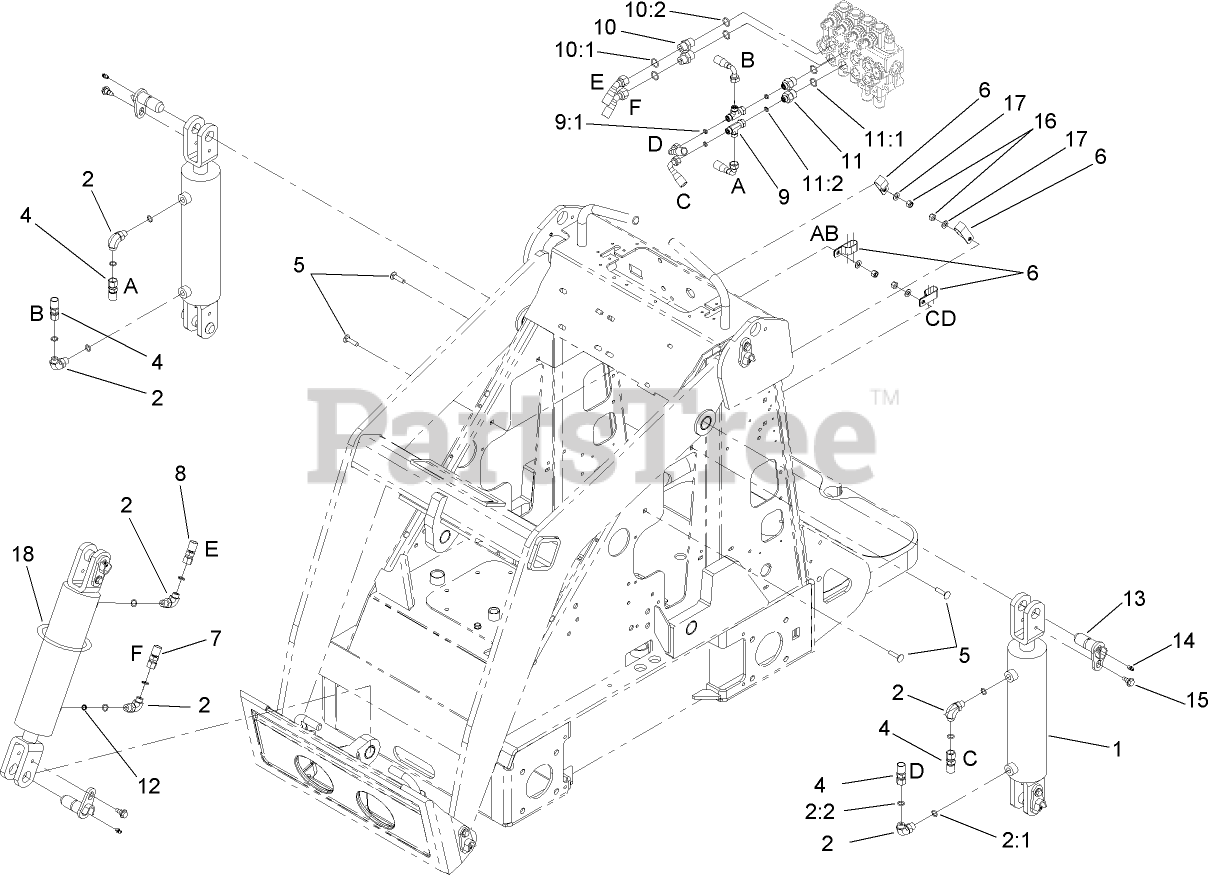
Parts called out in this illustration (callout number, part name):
1	CYLINDER-HYD
2	FITTING-ELBOW 90
2:1	O-RING
2:2	O-RING
4	HOSE-HYD
5	SCREW-CARR
6	CLAMP-R, DOUBLE
7	HOSE-HYD
8	HOSE-HYD
9	FITTING-HYD
9:1	O-Ring
10	FITTING-STRAIGHT
10:1	O-RING
10:2	O-RING
11	FITTING-STR
11:1	O-RING
11:2	O-RING
12	ORIFICE-PORT INSERT, ONE WAY
13	PIN-PIVOT
14	FITTING-GREASE
15	BOLT-SHOULDER
16	NUT-LOCK, NI
17	WASHER-PLAIN
18	TIE-CABLE
